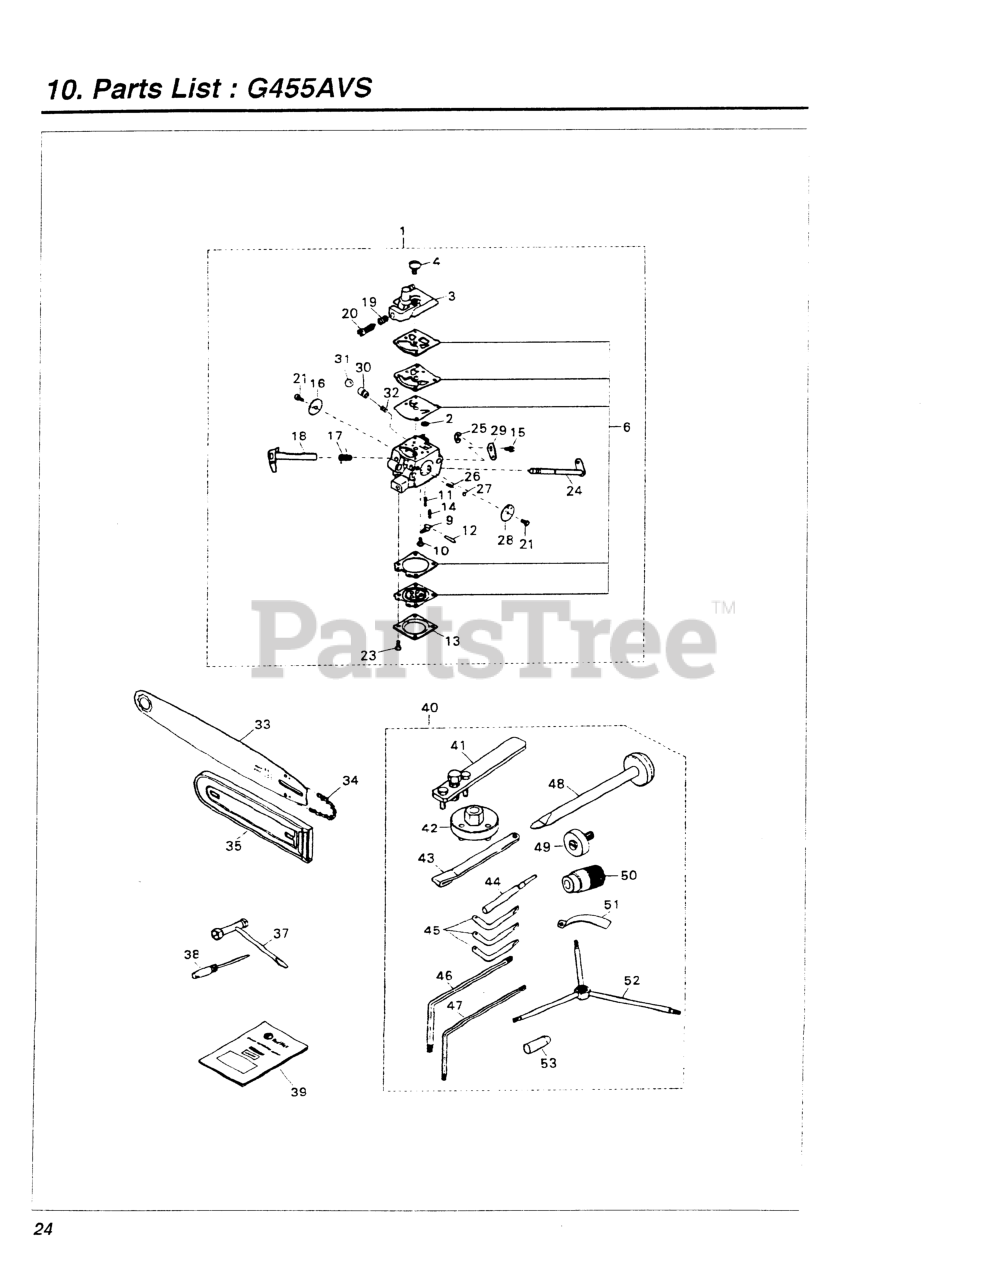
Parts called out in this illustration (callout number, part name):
1	CARBURETOR ASSEMBLY
3	COVER ASSEMBLY
9	LEVER
11	SPRING (USE 2867-81270)
12	PIN, METERING LEVER
14	VALVE, INLET
16	VALVE, THROTTLE
17	SPRING, RETURN
18	SHAFT, THROTTLE
19	SPRING, IDLE
21	SCREW (RPLS 3310-81360)
23	SCREW ASSEMBLY
24	SHAFT, CHOKE
26	SPRING
27	BALL, FRICTION
28	VALVE, CHOKE
33	BAR 16
34	CHAIN
37	WRENCH, PLUG
38	SCREWDRIVER
39	OWNERS MANUAL (G455AVS)
40	TOOL SET
41	PULLER ASSY
42	WRENCH (TOOL)
43	STOPPER (TOOL)
44	GUIDE (TOOL)
45	WRENCH (TOOL)
46	WRENCH (TOOL)
47	WRENCH (TOOL)
48	GUIDE (TOOL)
49	GUIDE (TOOL)
50	HOLDER (TOOL)
51	GUAGE, AIR GAP (TOOL)
53	GUIDE (TOOL)
